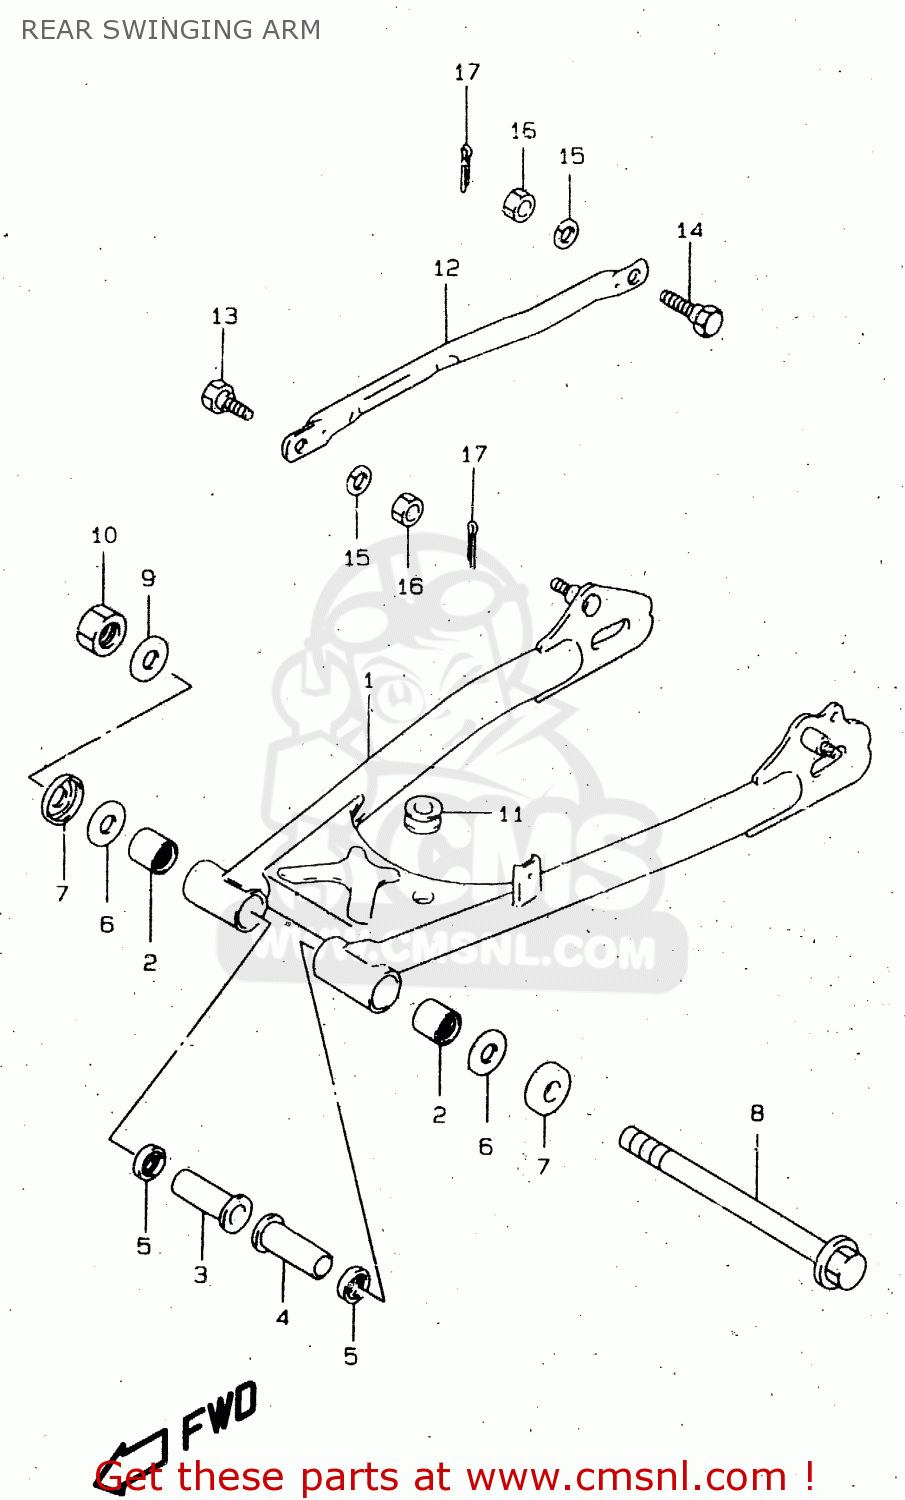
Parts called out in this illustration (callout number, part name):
1	SWINGINGARM ASSY,RR
2	BEARING(20X27X20)
3	SPACER,RR SWGARM PIVOT,R
4	SPACER,RR SWGARM PIVOT,L
5	SEAL,OIL(20X27X5)
6	WASHER
7	COVER,RR SWINGINGARM PIVOT
8	SHAFT,RR SWINGINGARM PIVOT
9	WASHER
10	NUT 14MM
11	CUSHION
12	TORQUE LINK,REAR BRAKE (
13	BOLT(8X22.5)
14	BOLT(8X26.5)
15	WASHER,LOCK
16	NUT
17	PIN 20X20
